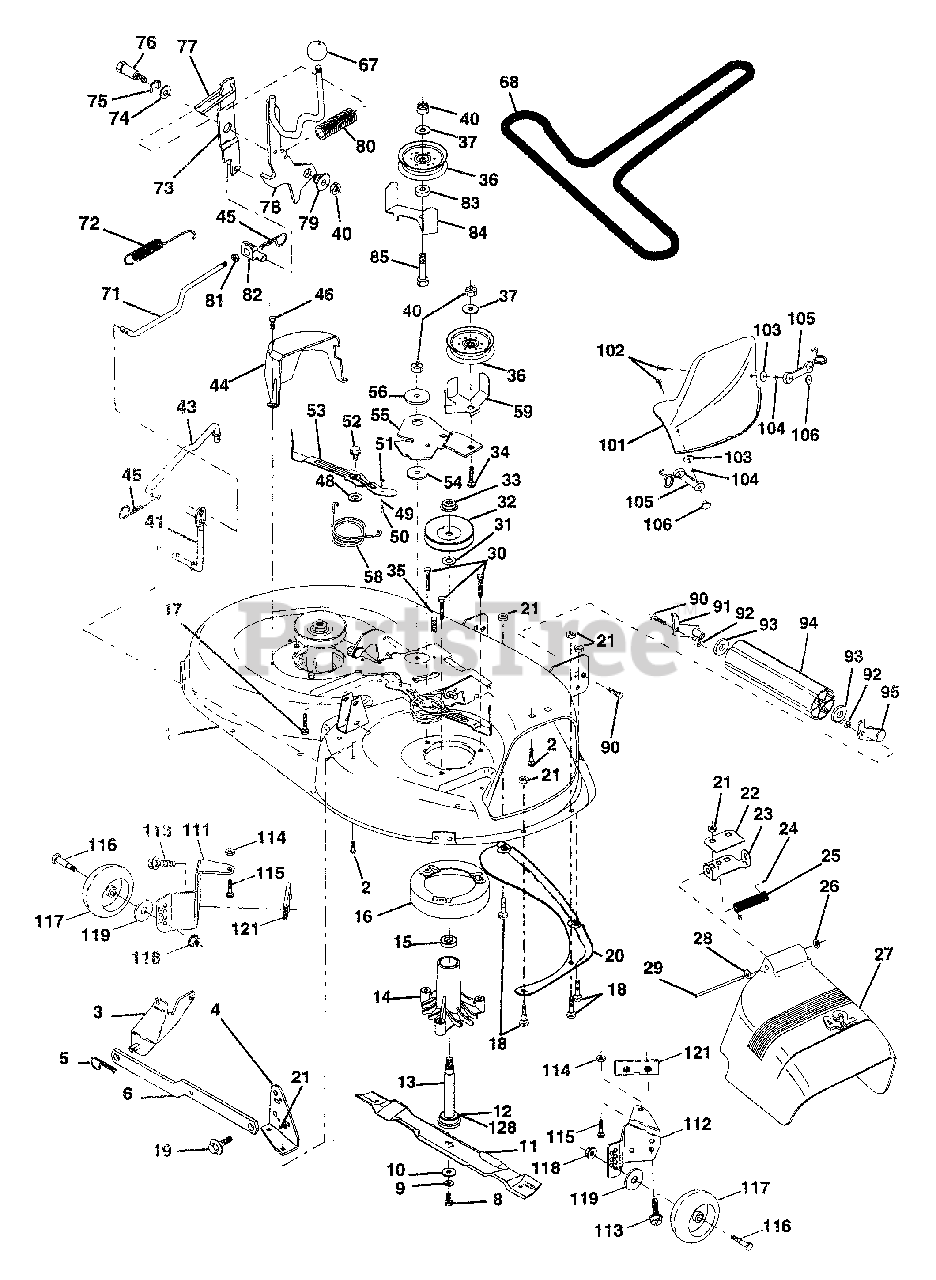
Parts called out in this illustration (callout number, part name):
1	Mower Housing Asm MWR 42"weldment T-Path
2	Bolt Rdhd Sqnk 5/16-18unc X3/4
3	Bracket Asm Fr Sway Bar 38/42
4	Bracket Asm Deck 42"sway Bar
5	Retainer Spring
6	Arm Suspension Rear
8	Bolt 3/8 - 24 X 1.25 Gr 8
9	Washer Lock Hvy 3/8
10	Washer Hard Blade Mower Vented
11	Blade Mower Mulching 42"
12	Bearing Ball #6024 (Mandrel)
13	Shaft Asm W/lower Bearing
14	Housing Mandrel Vented
15	Bearing Ball Mandrel
16	Stripper Mower Vented
17	Bolt Rdhd Sqnk 3/8-16 X 1-1/4
18	Bolt Rdhd Sqnk 5/16-18 X 5/8
19	Bolt Shoulder
20	Baffle Vortex 42
21	Nut Crownlock 5/16-18 UNC
22	Stiffener Bracket 42"deck
23	Bracket Deflector Mower 42"
24	Cap Sleeve 80x 112 Blk Mower
25	Spring Torsion Deflector 2 52
26	Nut Push Phos & Oil
27	Shield Deflector Mower 42" Blk
28	Washer 11/32 X 5/8 X 16 Ga
29	Rod Hinge 42"6 75 Wlg
30	Screw Thdrol Hex Head Zinc Mwr
31	Washer Spacer Mower Vented
32	Pulley Mandrel 42/44/50
33	Nut 9/16 Toplock Flng Oil Dip
34	Bolt Rdhd 3/8-16uncxl-3/4 Gr5
35	Fastner Christmas Tree
36	Pulley Idler Flat 3 060
37	Washer 13/32 X 13/16 X 16
40	Nut Crownlock 3/8-16 UNC
41	Rod Pivot W/nibs
43	Rod Clutch Secondary W/nibs
44	Guard Mandrel LH Black
45	Spring Retainer 1" Zinc/cad
46	Screw Hex Thd Cut 1/4-20x5/8 T
48	Washer Hardened Smaller
49	Roller Asm Cam Follower 42"dec
50	Bolt Shldr 10-24 Zinc Gr 5 42"
51	Nut Lock #10-24 Unc
52	Bolt Shoulder 5/16-18 Unc Blkz
53	Arm Asm Pad Brake
54	Washer Hardened
55	Arm Idler 42"mower LT/YT
56	Spacer Retainer Pm Mower
58	Spring Torsion Brakes
59	Guard TUV Idler
67	Knob Rd 1/2-13 Plstc Thds Blk
68	V-Belt Mower 42"
71	Rod Clutch Primary 38/42
72	Spring Return
73	Arm Clutch Secondary
74	Washer 25/32 X 1-5/8 X 16 Ga
75	Ring Klip #t5304-75
76	Bolt Shoulder 3/8-16 Unc 1 44
77	Keeper Spring 4 000
78	Arm Asm Clutch Primary
79	Bushing 747 Od X 794 Lg Brass
80	Spring Clutch Mower
81	Nut Hex Jam 3/8-16
82	Trunnion Adj 94
83	Washer Sintered
84	Keeper Belt Idler Fixed
85	Bolt RDHD 3/8-16 x 2-1/4 Gr.5
90	Bolt Fin Hex 3/8-16 UNC x 1
91	Bracket Asm Noseroller LH
92	Nut Lock Hex W/Ins 3/8-16 Unc
93	Washer 17/32 x 7/8 x 16 Ga.
94	Roller Nose 38 & 42
95	Bracket Asm Noseroller RH
101	Cover Mulching 42" Black
102	Screw
103	Washer #10
104	Washer Lock #10
105	Latch Asm Bagger
106	Nut Weld
111	Bracket Wheel Gauge LH 42" Deck
112	Bracket Gauge Wheel RH 42" Deck
113	Screw Thdrol 5/16-18 X 3/4
114	Nut Keps 5/16-18 UNC
115	Bolt Carriage 5/16-UNC x 1/2
116	Bolt Shoulder
117	Wheel Guage Donut
118	Nut Centerlock 3/8-16 UNC
119	Washer 3/8 x 7/8 x 14 Ga.
121	Bracket Extruded Guage Wheel
128	Washer Felt
